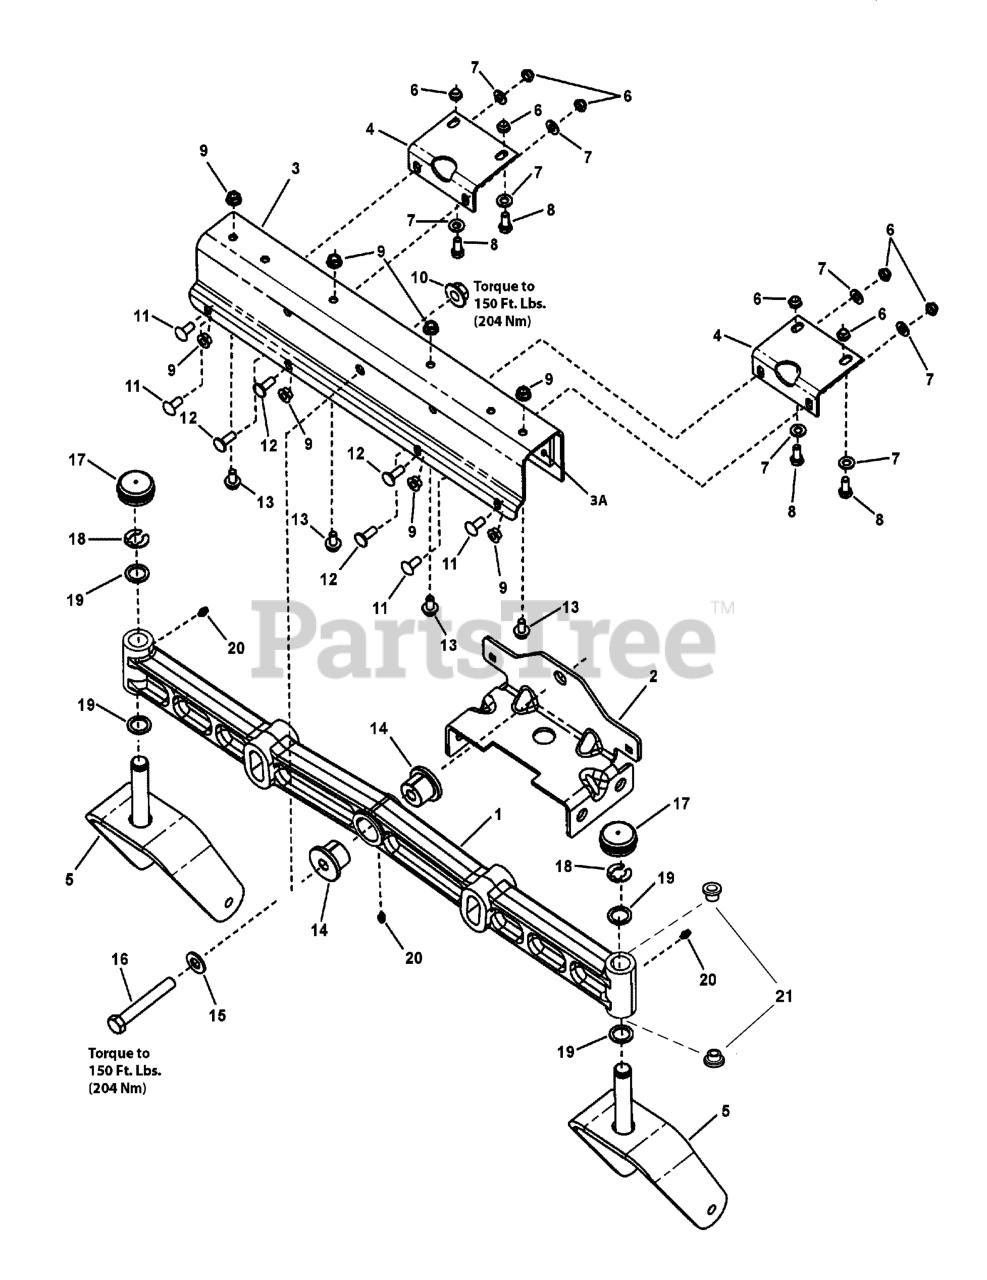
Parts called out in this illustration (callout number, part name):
1	AXLE, Casting
2	BRACKET, Hanger, Front, 46 / 52
3	BRACKET, Axle
3A	PLATE, Friction, Adhesive Backed
4	BRACKET, Axle Support
5	CASTER YOKE & SPINDLE
6	NUT, Hex Top Lock, 5/16-18, GR B
7	WASHER, Flat, 5/16
8	CAPSCREW, Hex Flange, 5/16-18 x 3/4, GR 5
9	NUT, Hex Flange Lock, 5/16-18, GR 5
10	NUT, Hex Flange, Two-Way Lock, 1/2-13
11	BOLT, Carriage, Short Neck, 5/16-18 x 3/4, GR 5
12	BOLT, Carriage, Short Neck, 5/16-18 x 7/8, GR 5
13	BOLT, 5/16-18 x 5/8" Hex Flange lock, GR 5, YZ
14	BUSHING, Axle Pivot
15	WASHER, Flat, 1/2
16	CAPSCREW, Hex Head, 1/2-13 x 3-1/2
17	CAP, Hub
18	RING, Klipring, For 3/4 Dia. Shaft
19	WASHER, 0.750 ID x 1.60 OD x .05 Thick
20	LUBE FITTING, 3/16" Press Fit
